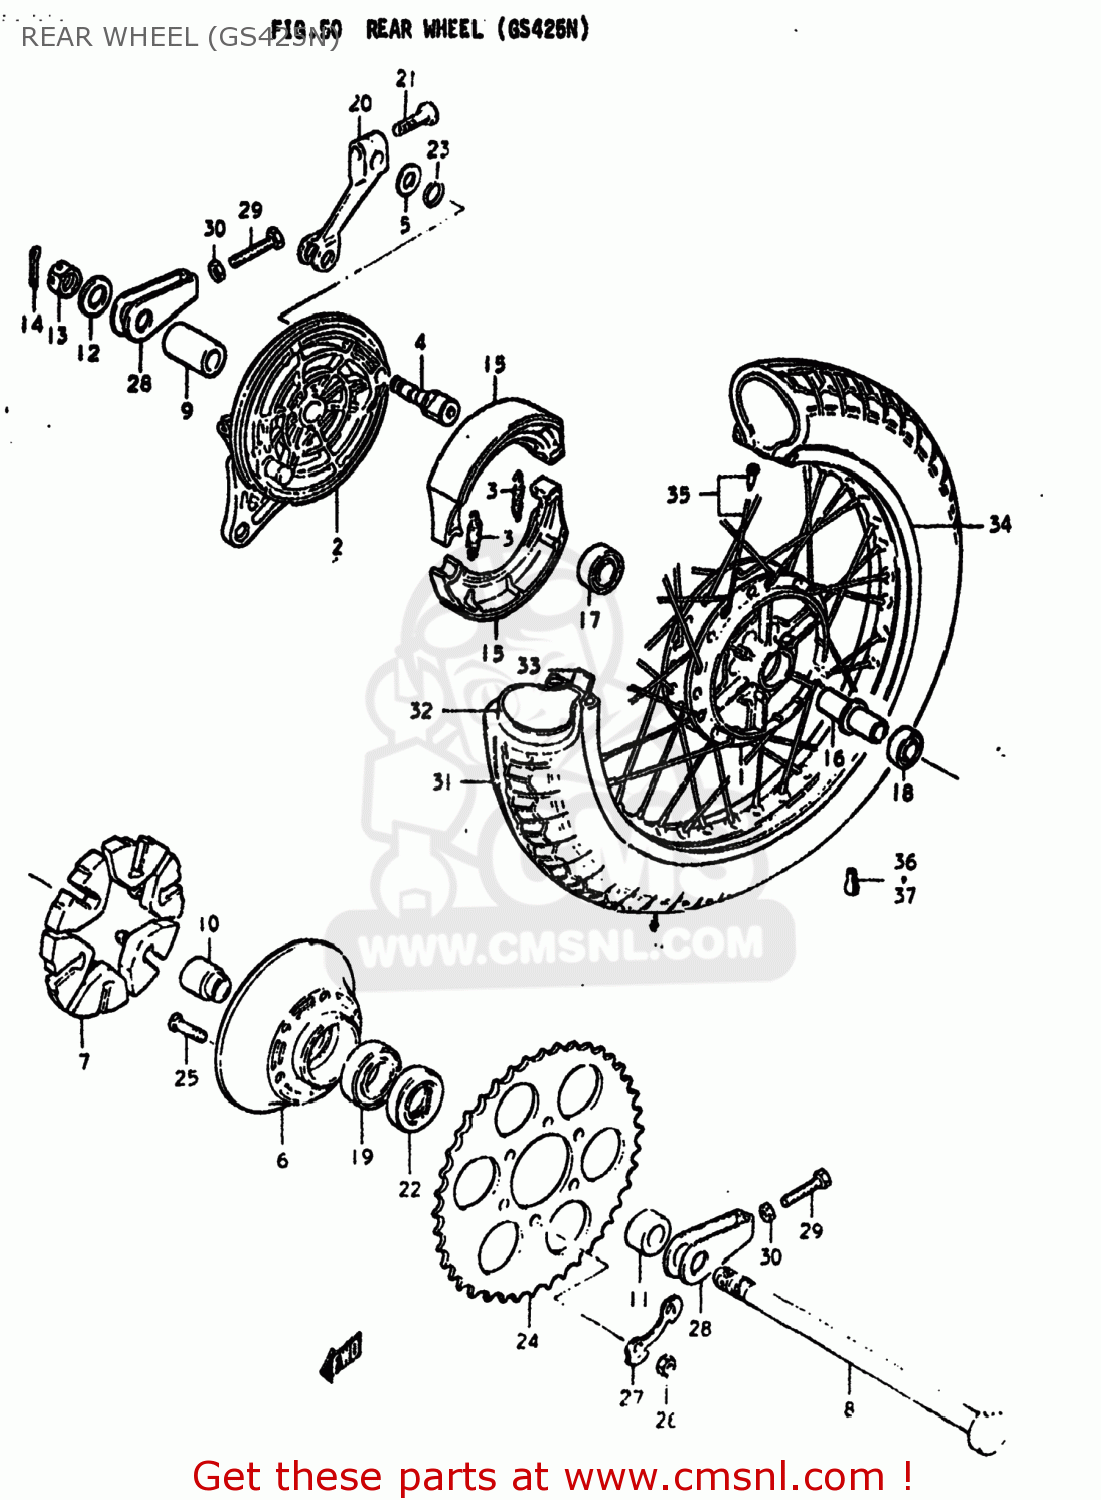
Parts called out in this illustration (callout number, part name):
1	DRUM,REAR HUB
2	PANEL,REAR HUB
3	SPRING,BRAKE SHOE
4	CAM,FRONT BRAKE
5	WASHER (15X24X1.6)
6	DRUM,REAR SPROCKET MOUNT
7	CUSHION,REAR DRUM
8	AXLE,REAR
9	SPACER(17.5X28X44.8)
10	SPACER,REAR HUB BEARING
11	SPACER(17X30.5X22.3)
12	WASHER (17X30X3.2)
13	NUT
14	PIN,COTTER
15	SHOE,BRAKE
16	SPACER
17	BEARING
18	BEARING
19	BEARING
20	LEVER,REAR BRAKE CAM
21	BOLT
22	OIL SEAL
23	O-RING,BOSS
24	SPROCKET,RR
25	BOLT
26	NUT
27	WASHER
28	ADJUSTER,CHAIN
29	BOLT
30	NUT
31	TIRE
32	TUBE ASSEMBLY,WHEEL,INNER
33	PROTECTOR,INNER TUBE
34	RIM,RR WHEEL
35	SPOKE SET,REAR WHEEL
36	BALANCER,WHEEL (B)
37	BALANCER,WHEEL (30G)
